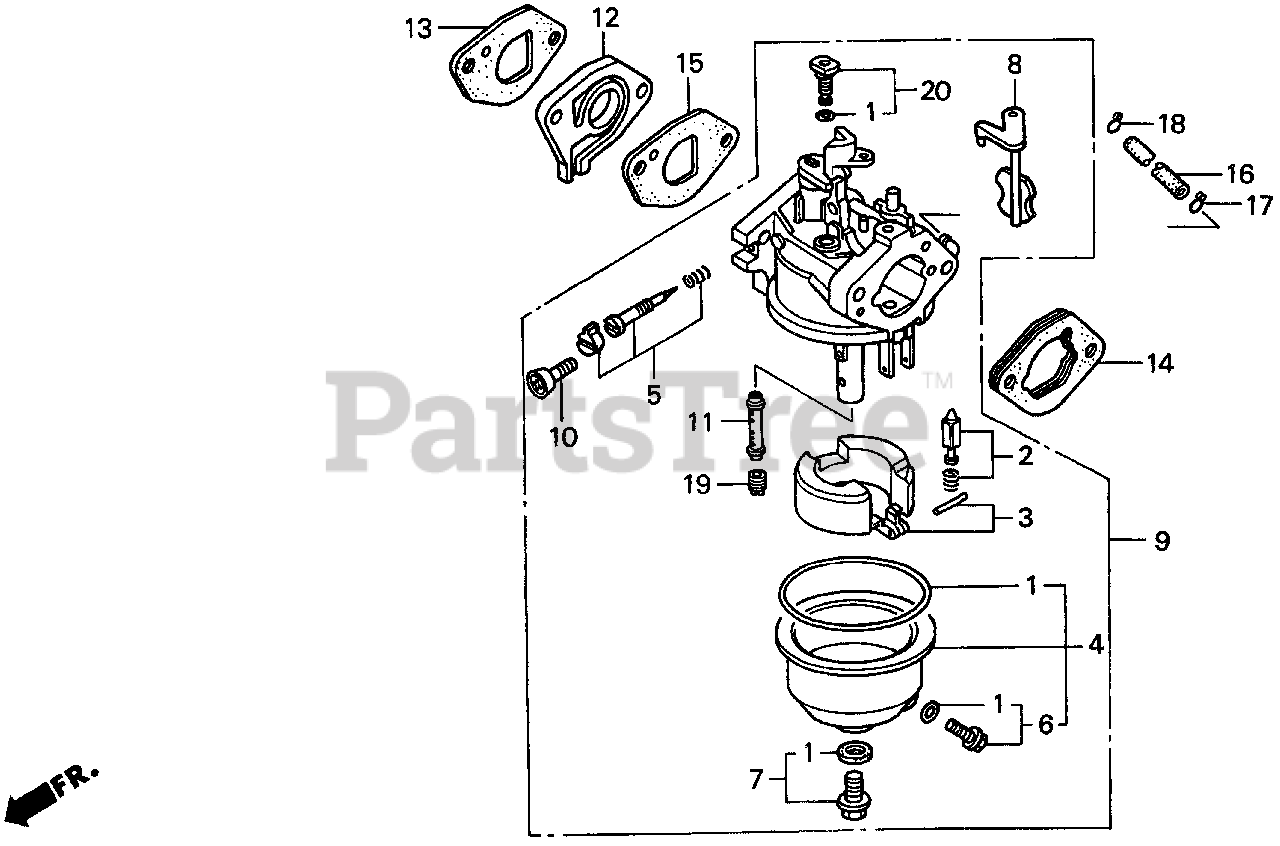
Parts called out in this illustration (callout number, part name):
1	GASKET SET (CARBURETOR NO.)
2	VALVE SET, FLOAT (CARBURETOR NO.) (SEAT NOT INCLUDED)
3	FLOAT SET
4	CHAMBER SET, FLOAT (CARBURETOR NO.)
5	SCREW SET
6	SCREW SET, DRAIN (Honda Code 1672187). (CARBURETOR NO.)
7	SCREW SET
8	CHOKE SET
9	CARBURETOR ASSY. (BE52B D)
10	SCREW, THROTTLE STOP
11	NOZZLE, MAIN (CARBURETOR NO.)
12	INSULATOR, CARBURETOR
13	GASKET, CARBURETOR (HPE)
14	SPACER, CARBURETOR
15	GASKET, CARBURETOR
16	TUBE, FUEL VALVE (170MM)
17	CLIP, TUBE (B8)
18	CLIP, TUBE (B10)
19	JET, MAIN (#50) Use from Engine SN BE52B B.
19	JET, MAIN (#52)
19	JET, MAIN (#55) (CARBURETOR NO.) Use up to Engine SN BE03A J.
20	JET SET, PILOT (#35)
